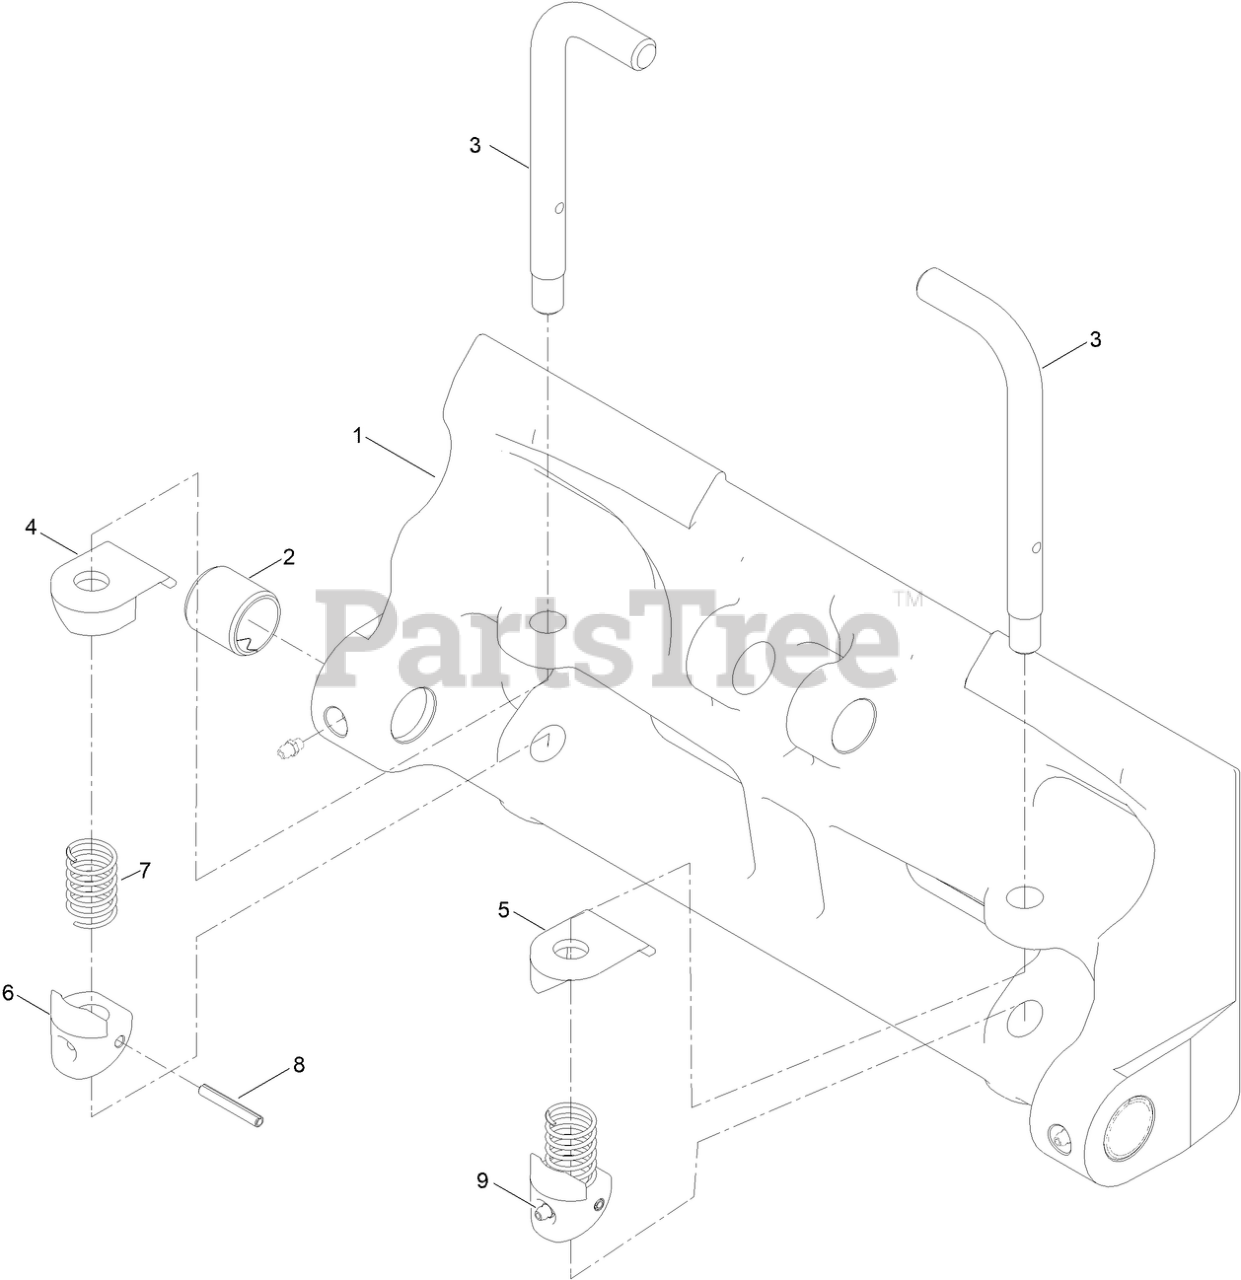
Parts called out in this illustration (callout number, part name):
2	BUSHING-SPRING
3	PIN-LOCKING,
4	STOP-PIN, LH
5	STOP-PIN, RH
6	CAM-QTACH
7	SPRING-COMPRESSION
8	PIN-ROLL
9	FITTING-GREASE
